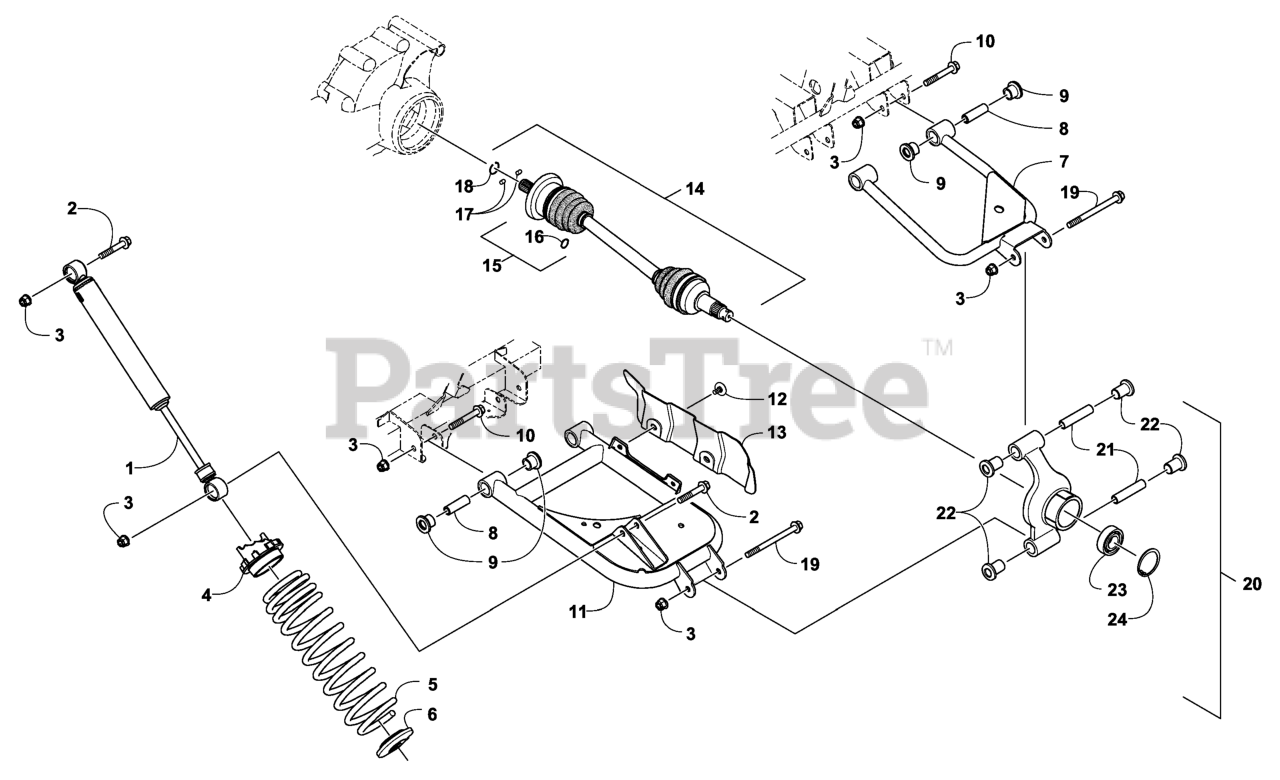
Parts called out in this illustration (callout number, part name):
1	BELT,DECK DRIVE
2	SPRING-EXTENSION
4	ADJUSTER-CAM, SPRING
5	Spring, Suspension
6	RETAINER-SPRING
7	A-ARM, REAR UPPER (RH ASM
7	A-ARM, REAR UPPER (LH ASM
8	COLLAR-SUSPENSION BUSHING
9	BUSHING-SUSPENSION, A-ARM
10	SCREW-HFH
11	A-ARM, REAR LOWER (RH ASM
11	A-ARM, REAR LOWER (LH ASM
12	SCREW-SELF TAP
13	GUARD-BOOT, REAR (RH)
13	GUARD-BOOT, REAR (LH)
14	KIT-HALFSHAFT REMOVAL
15	KIT-CV BOOT, UNIVERSAL
16	CIRCLI-HALFSHAFT, INTERNA
17	PIN-TRANSFER, LONG
18	CIRCLIP
20	KNUCKLE-REAR ASM
21	COLLAR-SUSPENSION BUSHING
22	BUSHING-SUSPENSION, REAR
23	BEARING-WHEEL
24	RING-RETAINING
